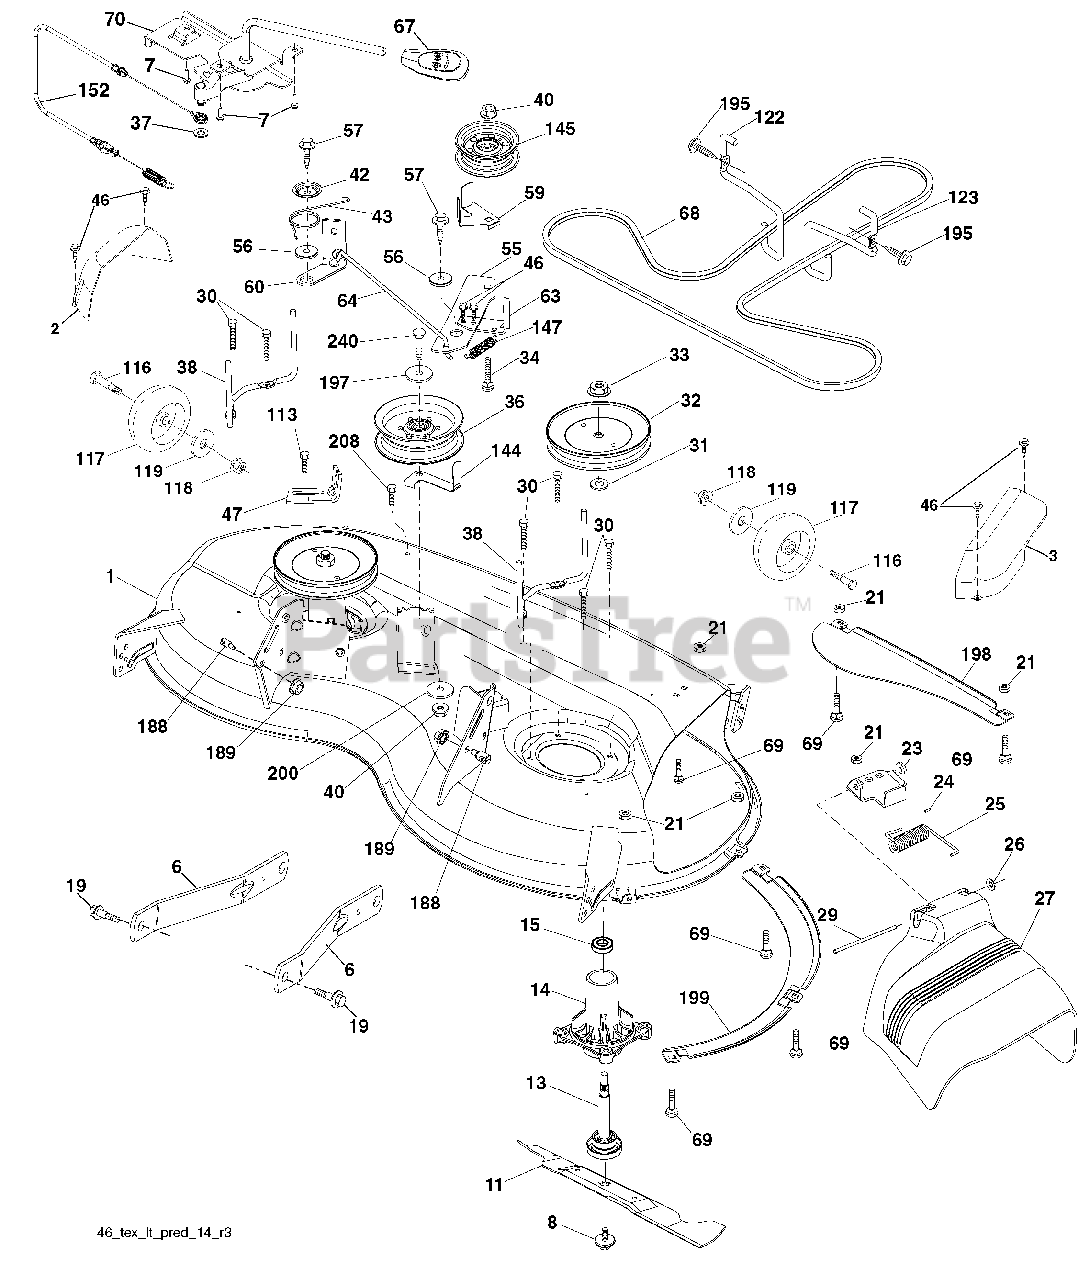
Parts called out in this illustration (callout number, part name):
1	Mower Housing
2	Cover Mandrel LH
3	Cover Mandrel RH
6	Arm Suspension
7	Screw #10 x 0.750
8	Bolt/Washer asm 7/16-20 unf
11	Blade, 46" Hi-Lift (For bagging or discharge)
11	Blade 46" Mulching
13	Shaft Assembly, Mandrel
14	Housing, Mandrel
15	Bearing, Ball, Mandrel
19	Bolt, Shoulder
21	Nut, Crownlock 5/16-18 unc
23	Bracket, Deflector
24	Cap, Sleeve
25	Spring, Torsion, Deflector
26	Nut, Push
27	Shield, Deflector
29	Rod, Hinge
30	Screw Thdrol Rolling Wsh Hd
31	Washer, Spacer
32	Pulley, Mandrel
33	Nut, Toplock, Flanged
34	Bolt Carr Sh. 3/8-16 x 1-1/2 Gr. 5
36	Pulley, Idler, Flat
37	Washer 13/32 x 13/16 x 16 Ga.
38	Keeper Belt LH Mandrel
40	Nut, Lock Flg. 3/8-16 unc
42	Spring Torsion Brake
43	Spring Torsion Retainer
46	Screw Thd Roll 1/4-20 x 5/8
47	Bracket Clutch Cable
55	Arm, Idler
56	Spacer, Retainer
57	Screw Hexwsh Thd 3/8-16 x 1
59	Guard, Tuv Idler (94)
60	Arm Brake Mower
63	Arm Brake Mower
64	Linkage Brake
67	Handle, Clutch Cable
68	V-Belt
69	Bolt Rdhd Sqnk 5/16-18 x 5/8
70	Clutch Asm. Manual
113	Screw 5/16-18
116	Bolt SHLD
117	Wheel Gauge
118	Nut Centerlock 3/8-16 unc
119	Washer 3/8 x 7/8 x 14 Ga.
122	Keeper Belt Eng. LH
123	Keeper Belt Eng. RH
144	Keeper Belt
145	Pulley Idler
147	Spring Return
152	Cable Clutch Manual w/Spr.
188	Stud Fastener
189	Nut Lock Hex Flange
195	Screw Hexwsh Thdr 3/8-16 x 3/4
197	Washer 13/32 x 13/16 x 12 Ga.
198	Baffle Center Front
199	Baffle Front RH
200	Washer 13/32 x 1/2 x 11 Ga.
208	Screw 3/8-16 x 1/2
240	Bolt Fin Hex 3/8-16 x 2-1/4 Gr. 5
240	Mandrel Assembly
240	Replacement Mower, Complete
